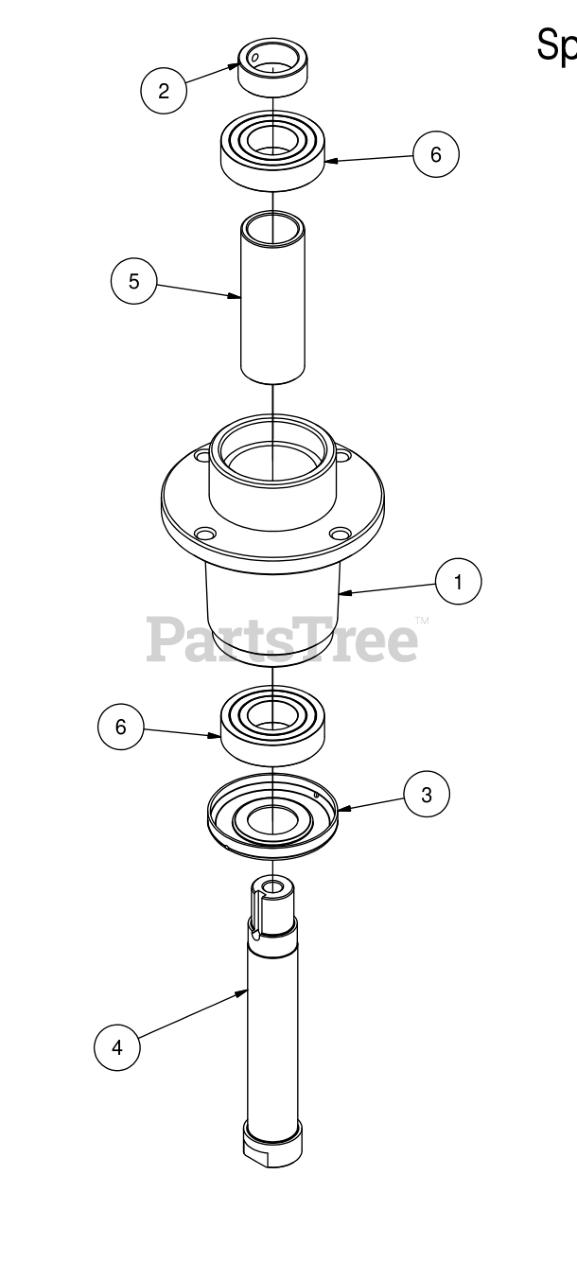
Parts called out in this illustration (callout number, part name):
1	Spindle Housing
2	Locking Collar w/ 1/4"-20 Set Screw
3	Spindle Dust Cap
4	Spindle Shaft
5	Spindle Spacer
6	Bearing-6206
